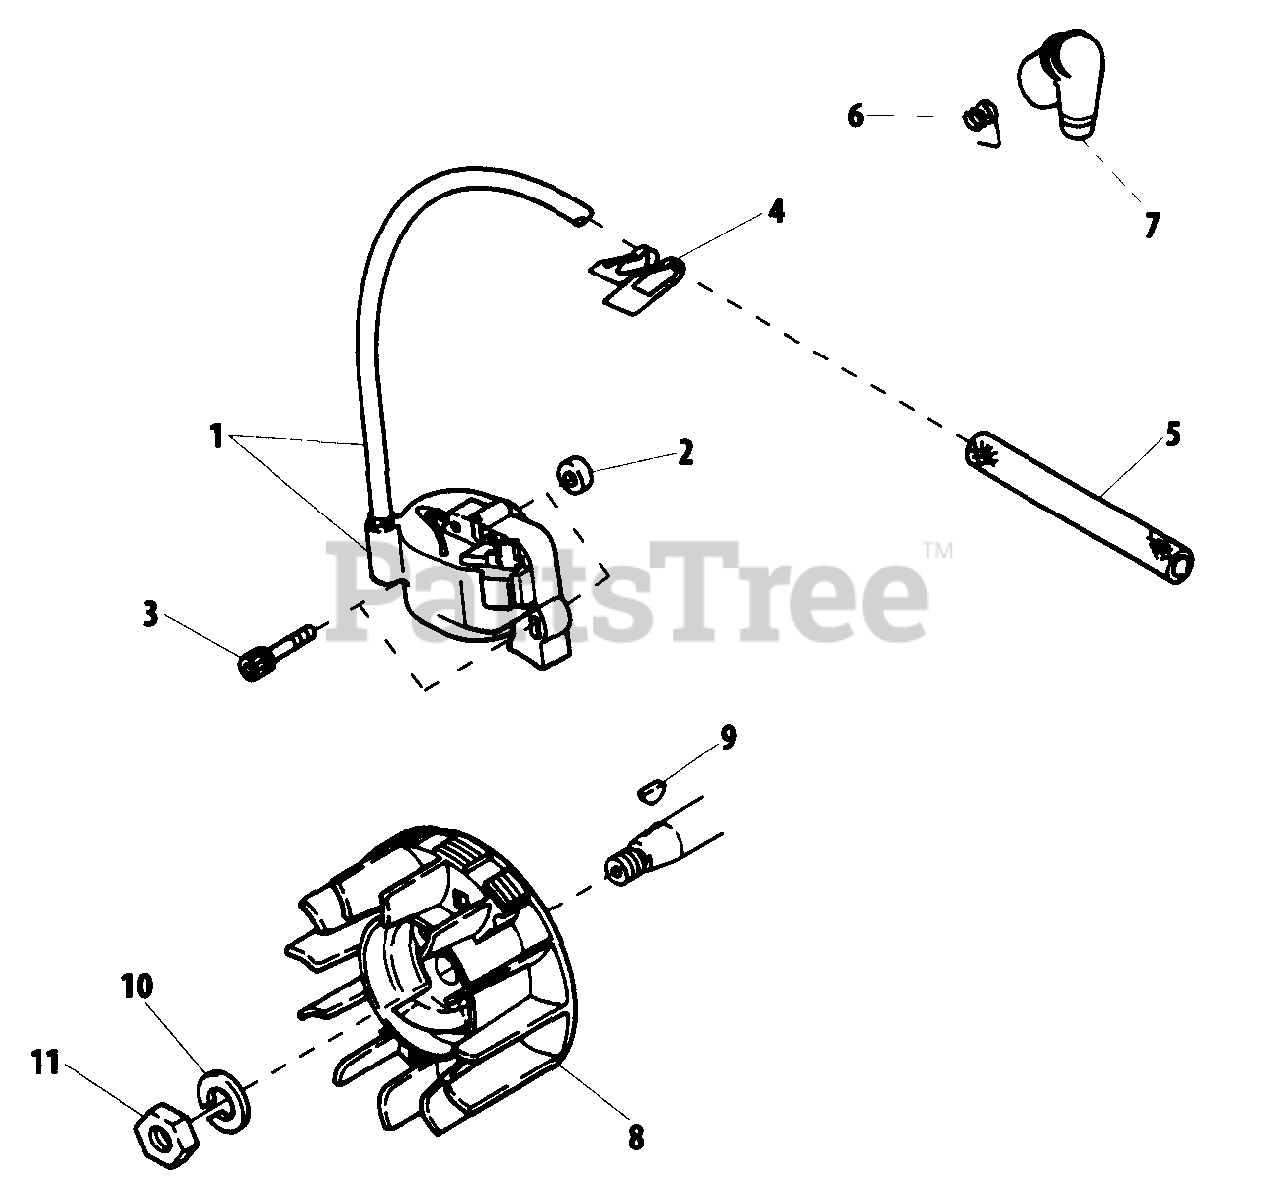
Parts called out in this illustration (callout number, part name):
1	COIL, IGNITION
2	INSULATOR
3	SCREW - 4X24
4	CLIP
5	TUBE
6	TERMINAL, SPARK PLUG CAP
7	CAP, SPARK PLUG
8	FLYWHEEL
9	KEY - 3X10
10	LOCKWASHER - 8
11	NUT
